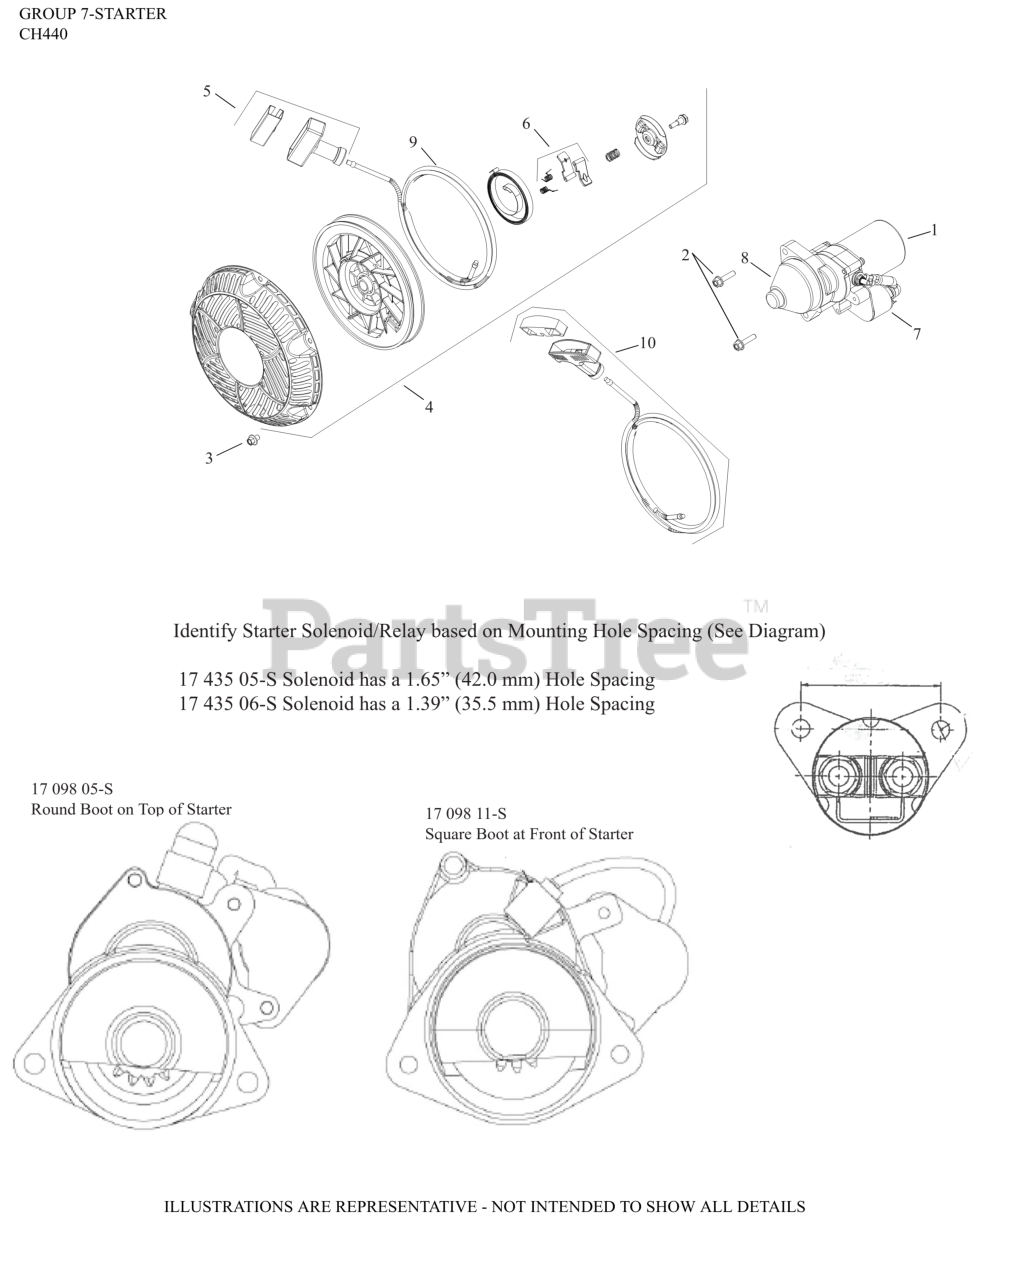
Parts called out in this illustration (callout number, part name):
1	ELECTRIC STARTER-BENDIX DRIVE
3	SCREW, M6 X 8 HEX FLANGE HEAD
4	RETRACTABLE STARTER ASSY-(#1716522S)
5	KIT, HANDLE
6	KIT, PAWL REPAIR
8	KIT, STARTER DRIVE
